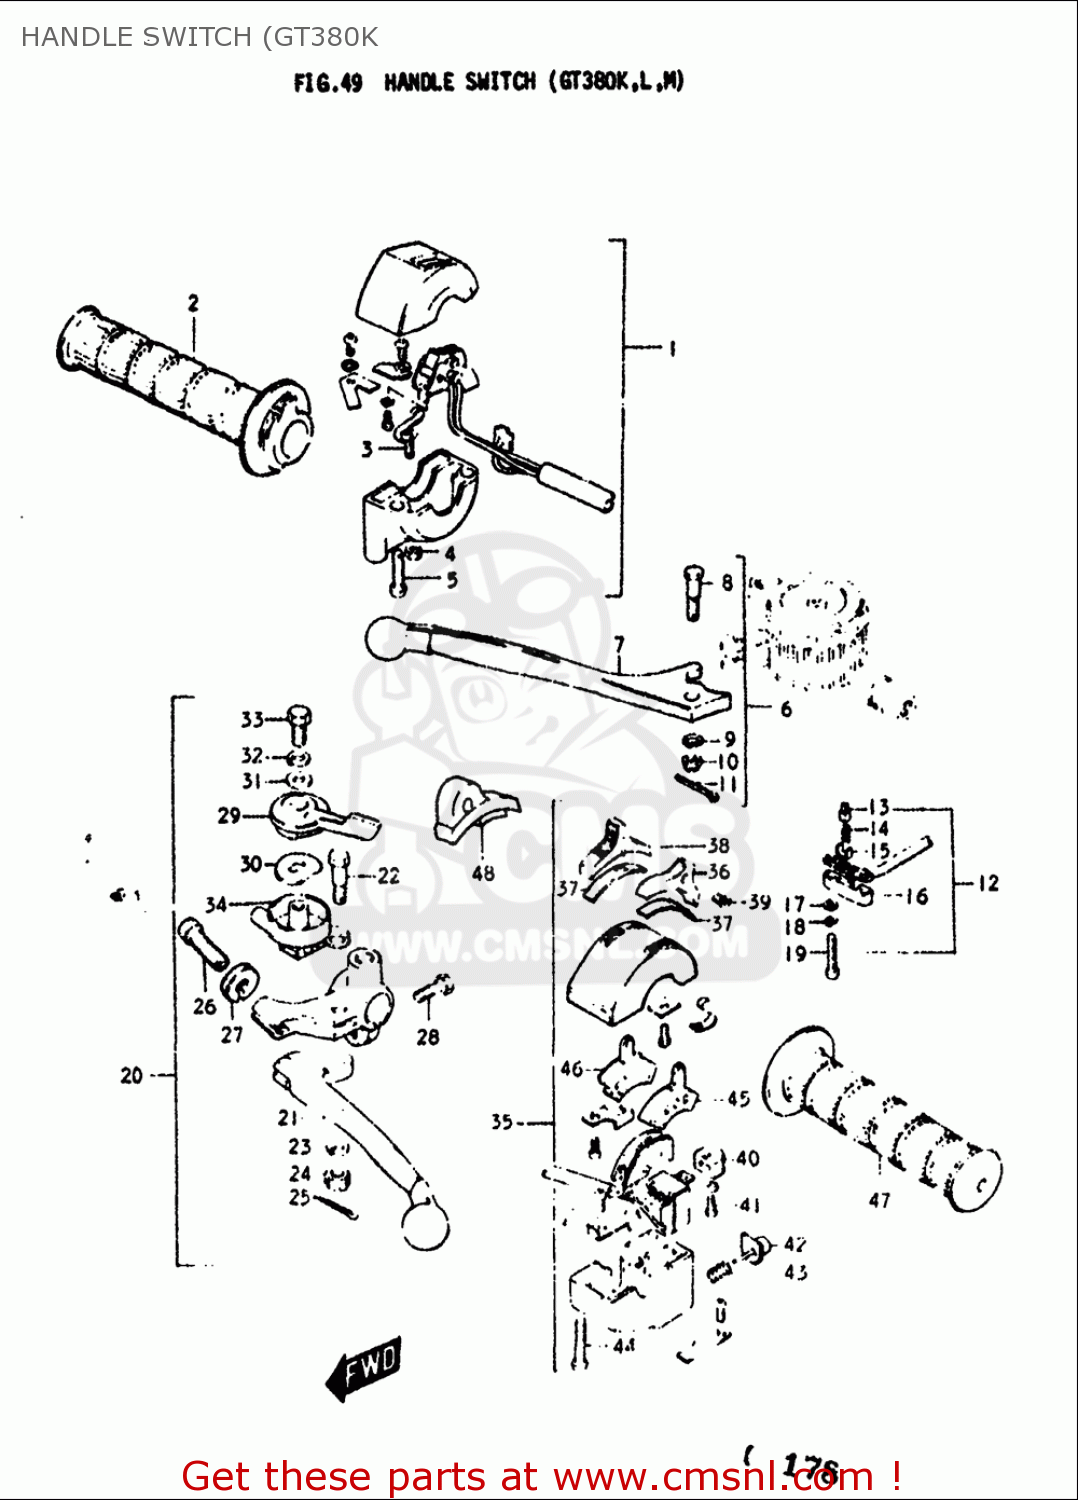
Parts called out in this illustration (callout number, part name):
2	GRIP,THROTTLE
3	ADJUSTER, THROTTLE
4	NUT
5	SCREW
7	LEVER,BRAKE
8	BOLT
9	WASHER,LOCK
10	NUT,LEVER FITTNG
11	PIN 16X20
12	SWITCH ASSY,STOP
13	CONTACT,SWITCH
14	CONTACT,SWITCH
15	CONTACT,SWITCH
16	COVER,FR BK TERMINAL BASE
17	WASHER
18	WASHER,LOCK
19	SCREW
20	LEVER ASSY,CLUTCH
21	LEVER,CLUTCH
22	BOLT,LEVER PIVOT
23	WASHER,LOCK
24	NUT,LEVER FITTNG
25	PIN 16X20
26	ADJUSTER,CABLE
27	NUT,CABLE ADJUSTER
28	BOLT
29	LEVER
30	WASHER,ADJUSTER
31	WASHER(6.5X16X1)
32	WASHER,LOCK
33	BOLT
37	PLATE,SWITCH KNOB
38	KNOB
39	SCREW
41	SCREW
42	BUTTON,HORN
43	SPRING,BUTTON
44	SCREW
45	BLOCK, LIGHTING SWITCH
46	GRIP,L
